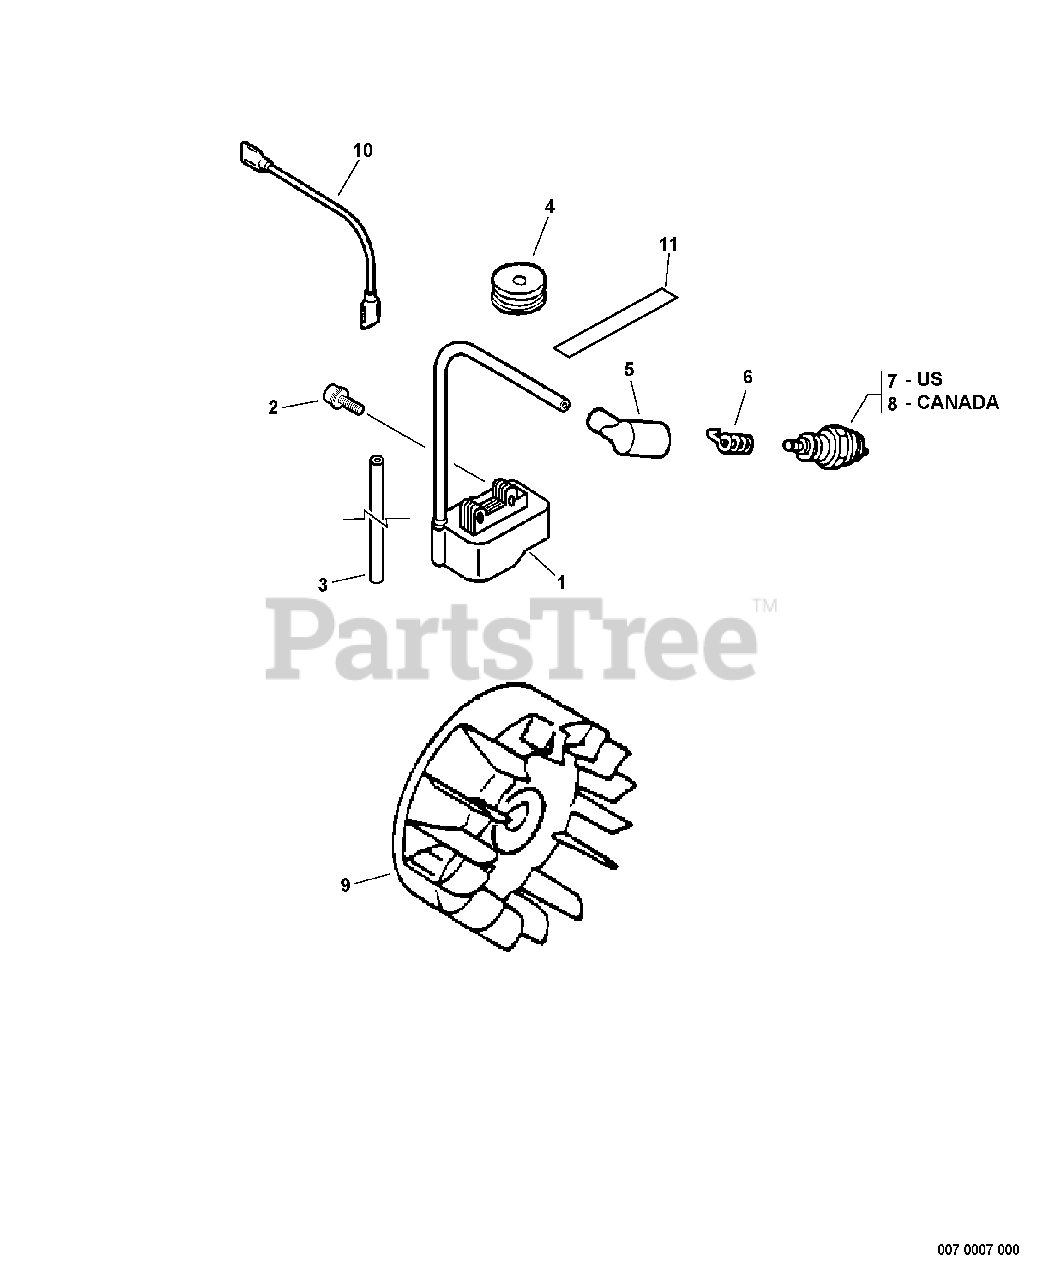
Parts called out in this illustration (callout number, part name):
1	COIL, IGNITION
2	BOLT 4×20
3	TUBE, INSULATOR
5	CAP, SPARK PLUG
6	TERMINAL, SPARK PLUG
7	SPARK PLUG - BPM8Y
8	SPARK PLUG - BPMR8Y
9	FLYWHEEL
10	LEAD - GROUND
11	LABEL, SPARK PLUG - BPM8Y
